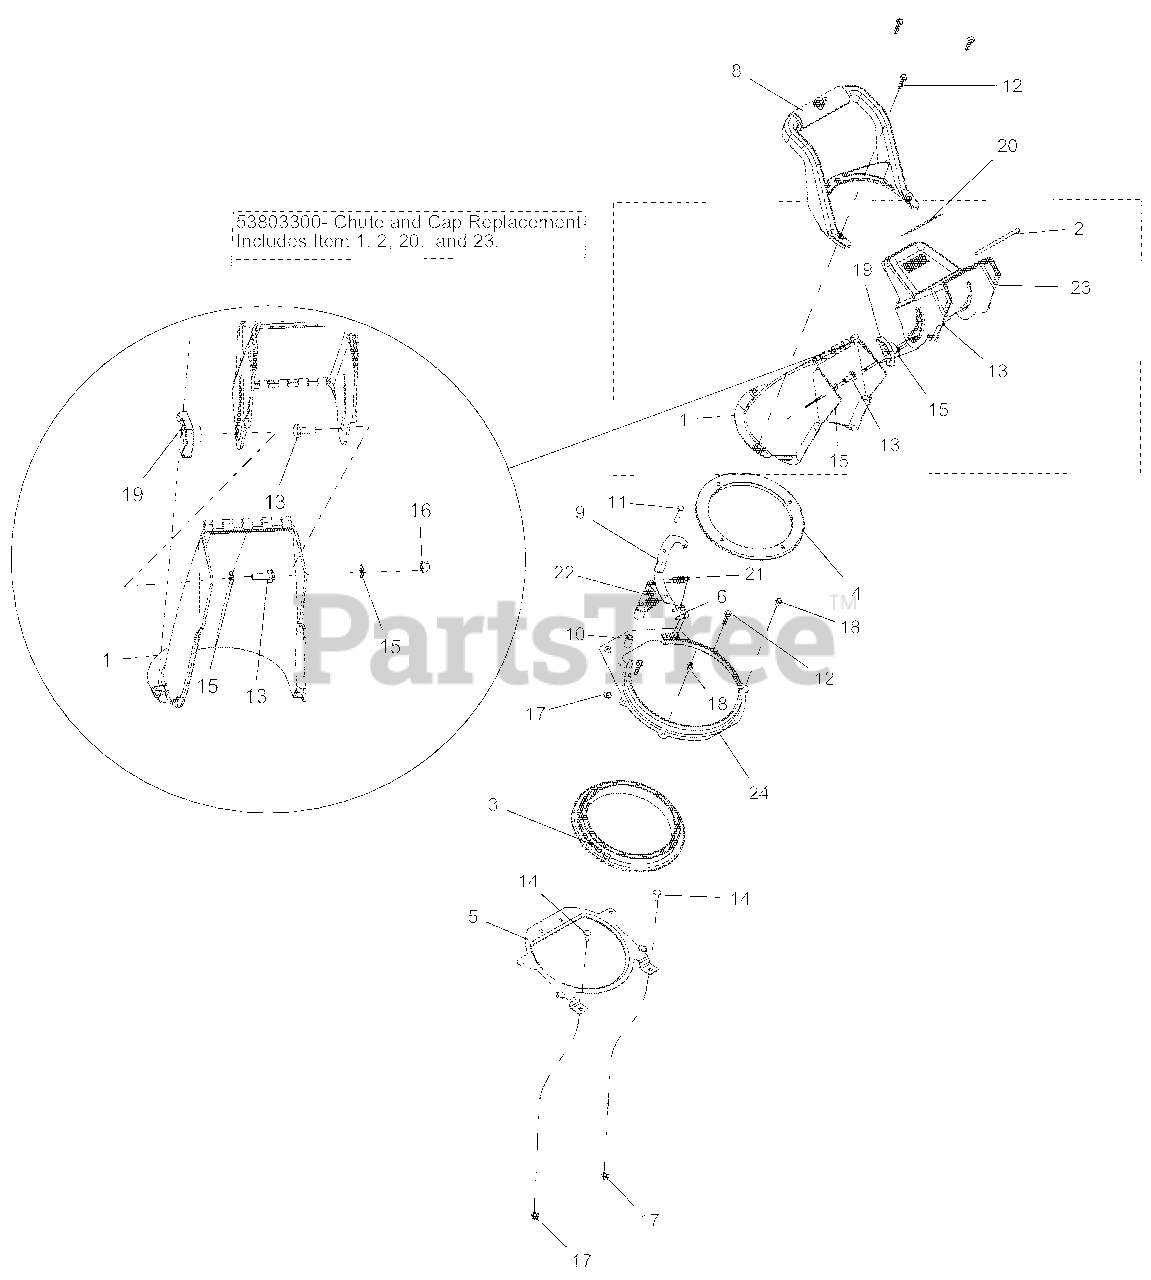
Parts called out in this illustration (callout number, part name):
1	CHUTE, SINGLE STAGE
2	ROD, CONNECTING, 1/4 X 4-1/2
3	GEAR, CHUTE RING
4	GUARD, WATER
5	RING, CHUTE MOUNT - LOWER
6	BRKT, SPRG
8	CHUTE, HANDLE SINGLE STAGE
9	PAWL ARM STOP
10	BSHG, SLV .265X.505X.995
11	@BLT-HEX .25-20X1.50 GR5 YWZC
12	SCR-TAP .25-10X1.25 HWH YWZC
13	BLT,RNHDRECSHNK .31-18X1.00
14	@BLT-RDHDSQNK .25-20X.75 G5YZ
15	@WSHR-FL-STL.344X.688X.065YWZC
16	@NUT-LK-NYL .312-18 YWZC
17	@NUT-LK-TOP-FLG .25-20 YWZC
18	SCR-TAP .25-20X.50 HWH TR YWZ
19	KNOB,WING .31-18 UNC NYL/TALC
20	DECAL, DANGER
21	SPRG, TENSION .052X.520X1.74
22	KIT, PAWL ARM REPLACEMENT
23	KIT, CAP REPLACEMENT
24	RING, CHUTE MOUNT - UPPER
